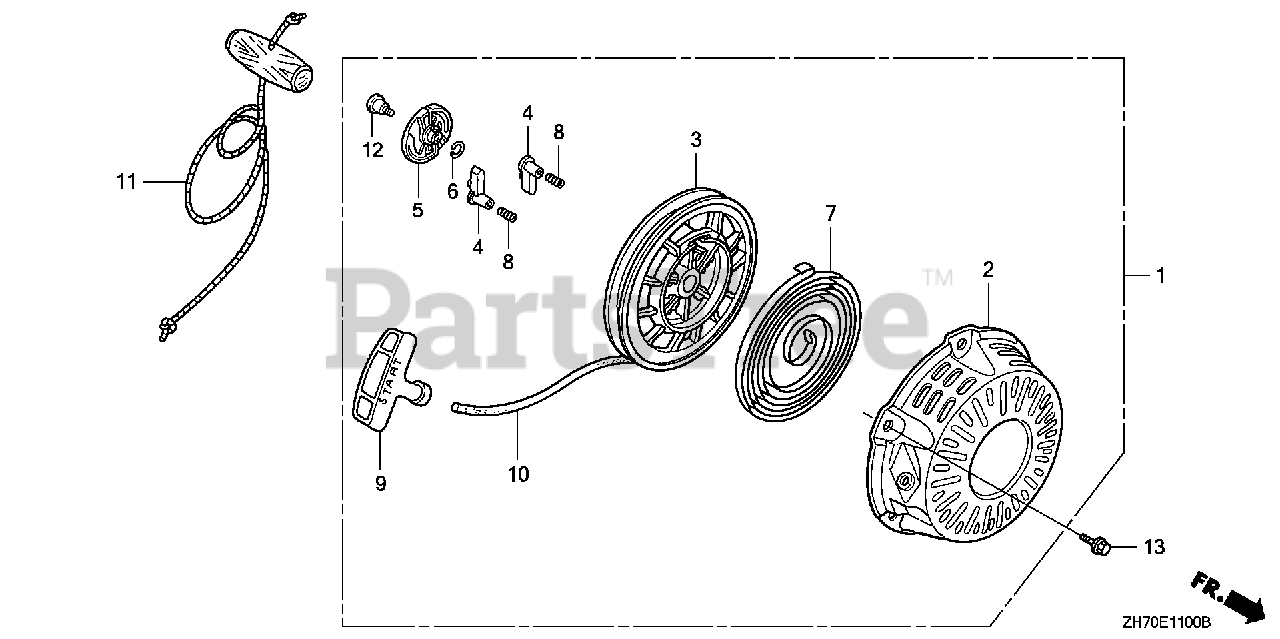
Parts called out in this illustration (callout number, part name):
1	STARTER ASSY., RECOIL *R280* (POWER RED)
1	STARTER ASSY., RECOIL *NH1* (BLACK)
2	CASE, RECOIL STARTER *R280* (POWER RED)
2	CASE, RECOIL STARTER *R8* (BRIGHT RED)
2	CASE, RECOIL STARTER *NH1* (BLACK)
3	REEL, RECOIL STARTER (NATURAL)
4	RATCHET, STARTER
5	GUIDE, RATCHET
6	SPRING, FRICTION
7	SPRING, RECOIL STARTER
8	SPRING, RETURN
9	GRIP, STARTER
9	KNOB, RECOIL SRARTER
10	ROPE, RECOIL STARTER
12	SCREW, SETTING
13	BOLT, FLANGE (6X10)
